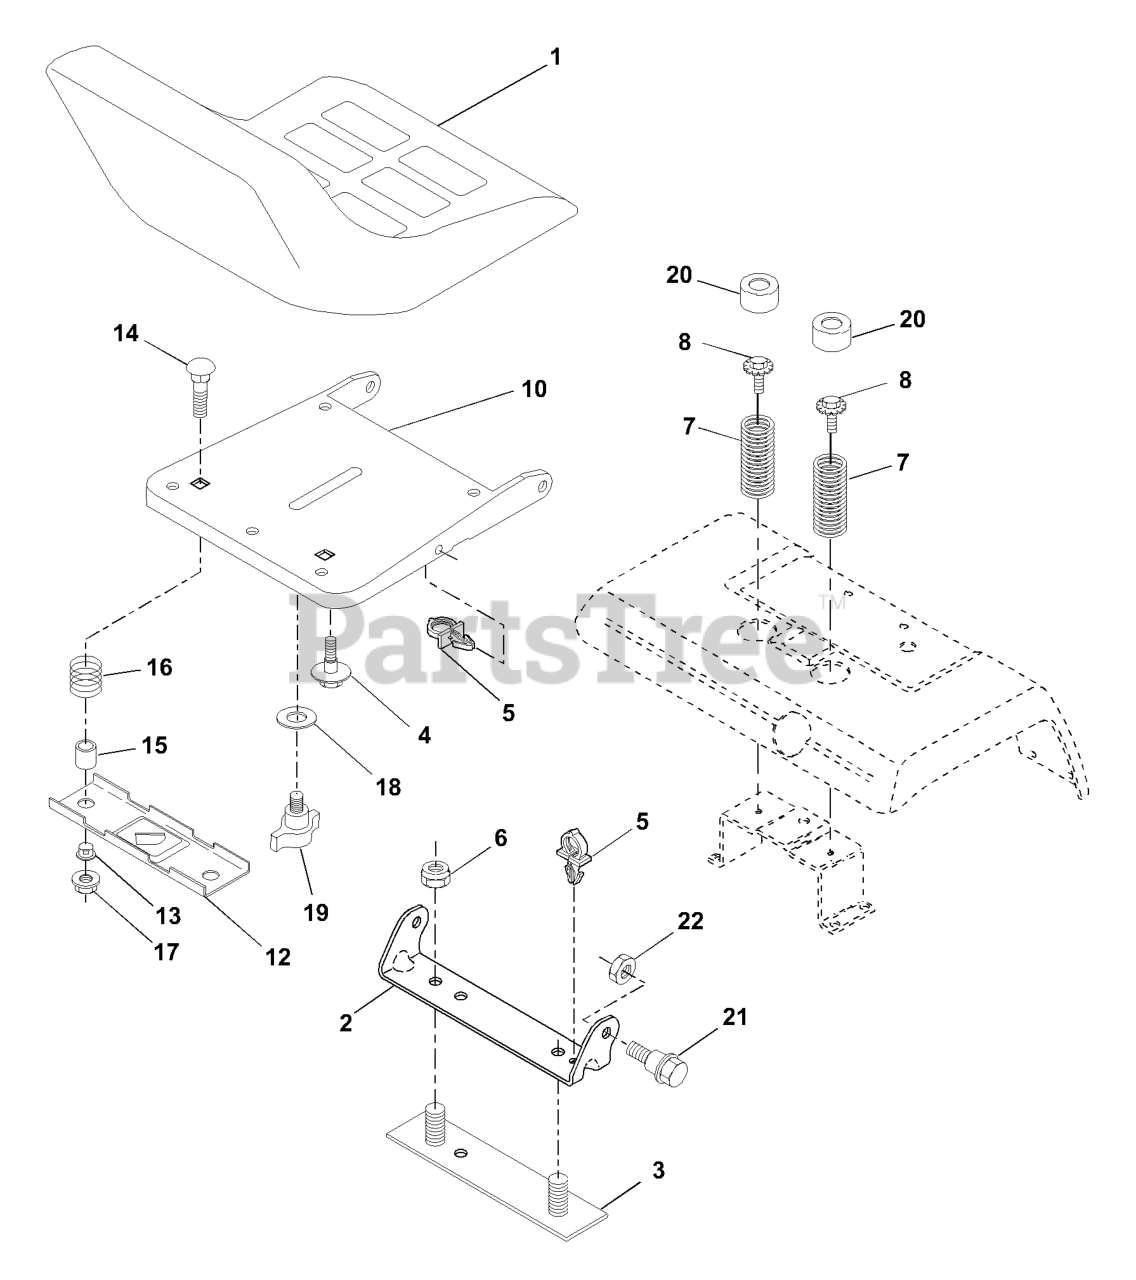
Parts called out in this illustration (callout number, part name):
1	SEAT, GRAY
2	SEAT PIVOT BRKT
3	STRAP
4	BOLT,SHOULD
6	NUT
7	SPRING COMPRESSION
8	BOLT.5/16-18UNCX3/4 W/SEMS.BLK
10	PAN, SEAT
12	BRKT SWITCH
14	BOLT.ROUND.HEAD.SQUARE.NECK
15	SPACER SPLIT
16	SPRING COMPRESSED
17	NUT T
19	KNOB.SEAT.ADJ.WINGNUT
20	CAP SPRING
21	BOLT.SHOULDER.5/16-18
22	NUT.71038.31-18.HEX.NYLOCK
